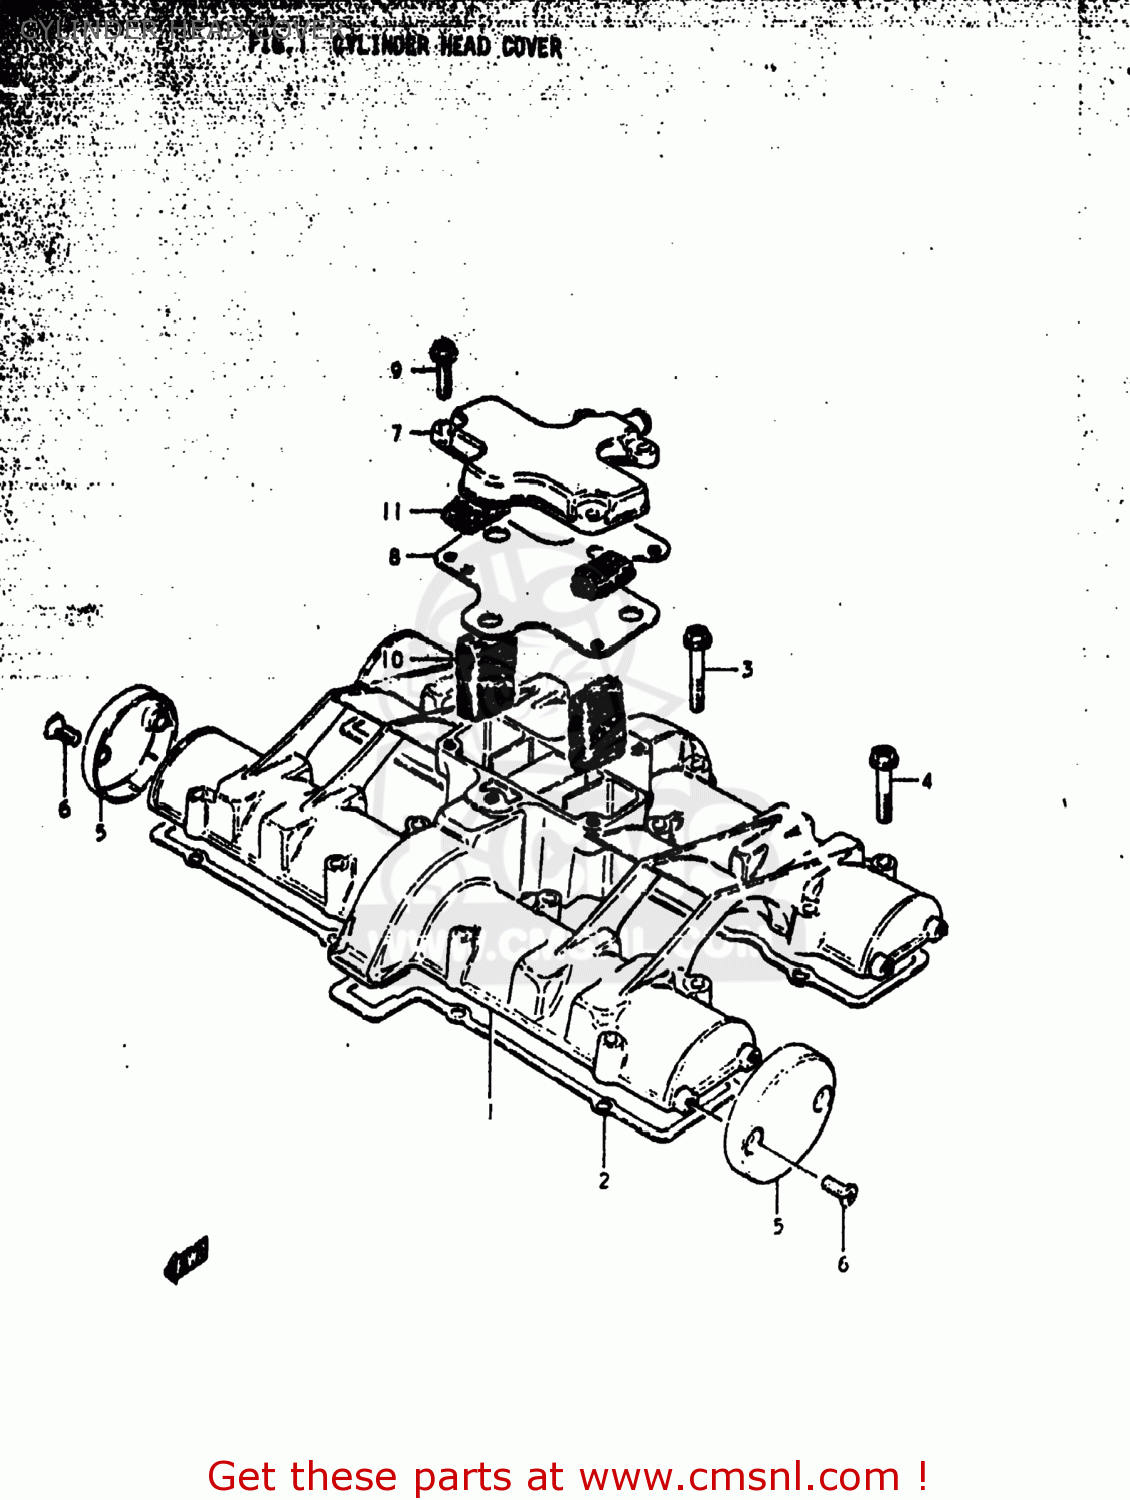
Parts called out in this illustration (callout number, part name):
1	COVER,CYLINDER HEAD
2	GASKET,CYLINDER HEAD COVER (MCA)
3	BOLT
4	BOLT 6X35
5	CAP,CYLINDER HEAD COVER
6	SCREW
7	COVER,BREATHER
8	GASKET (MCA)
9	BOLT
10	COVER,BREATHER
11	SEPARATOR,OIL BREATHER
